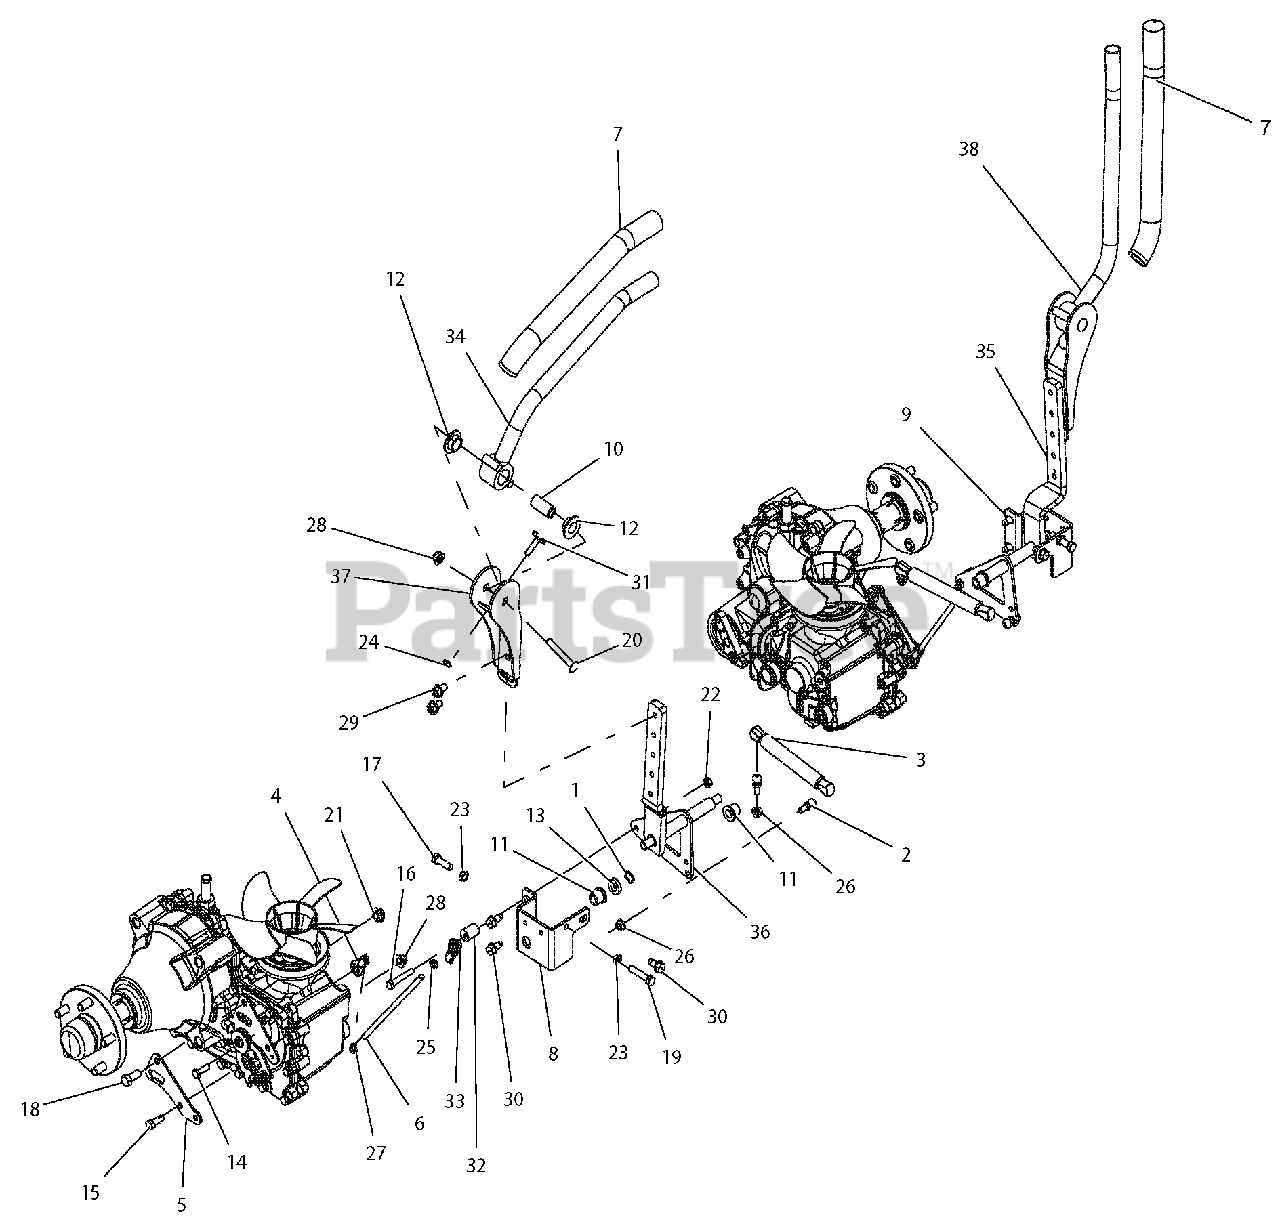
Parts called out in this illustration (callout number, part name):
1	WAVE WASHER .531X.781X.125 FH
2	STUD-BALL
3	DAMPER,
4	ALIGNABALL, 5/16 LH THREAD
5	BRKT., CONTROL MTG-BLACK
6	ROD, STEERING
7	GRIP, HANDLEBAR
8	BRKT, RH CONTROL ARM STOP-RED
9	BRKT, LH CONTROL ARM STOP-RED
10	SPCR, STEERING ARM
11	BHSG-FLG .500X.750X.750X.125
12	BSHG, FLANGE .762 X 1.48 X .44 NYLON
14	BLT-HEX .31-18X1.00 GR5 YWZC
15	BLT-HEX .38-16X1.00 GR5 YWZC
16	BLT-HEX .31-18X2.00 GR5 YWZC
17	BLT-HEX .38-16X1.25 GR5 YWZC
18	BLT-HEX .44-14X1.00 GR5 YWZC
19	BLT-HEX .38-16X1.75 GR5 YWZC
20	BLT-RHDSSQNK .38-16X2.50 G5YZ
21	NUT-LK-NYL-FLG .44-14 YWZC
22	NUT-LK-CTR .31-18 YWZC
23	NUT, JAM .375-16 YWZC
24	NUT, JAM .312-18 YWZC
25	NUT-JAM
26	NUT, LK-TOP-FLG .312-18 YWZC
27	NUT, JAM -LH .31-24 YWZC
28	NUT-LK-NYL-FLG .38-16 YWZC
29	BLT-SERHFWH .38-16X.62 YWZC
30	SCR-TAP .38-16X.75 HWH TR YWZ
31	BUMPER, STUD MOUNTED
32	ECCENTRIC
33	ALIGNABALL, 5/16 RH THREAD
34	WLDMT, RH STEERING ARM
35	WLDMT, LH LOWER CONTROL ARM
36	WLDMT, RH LOWER CONTROL ARM
37	MOUNT, STEERING ARM, ADJUSTABLE-BLACK
38	WLDMT, LH STEERING ARM
